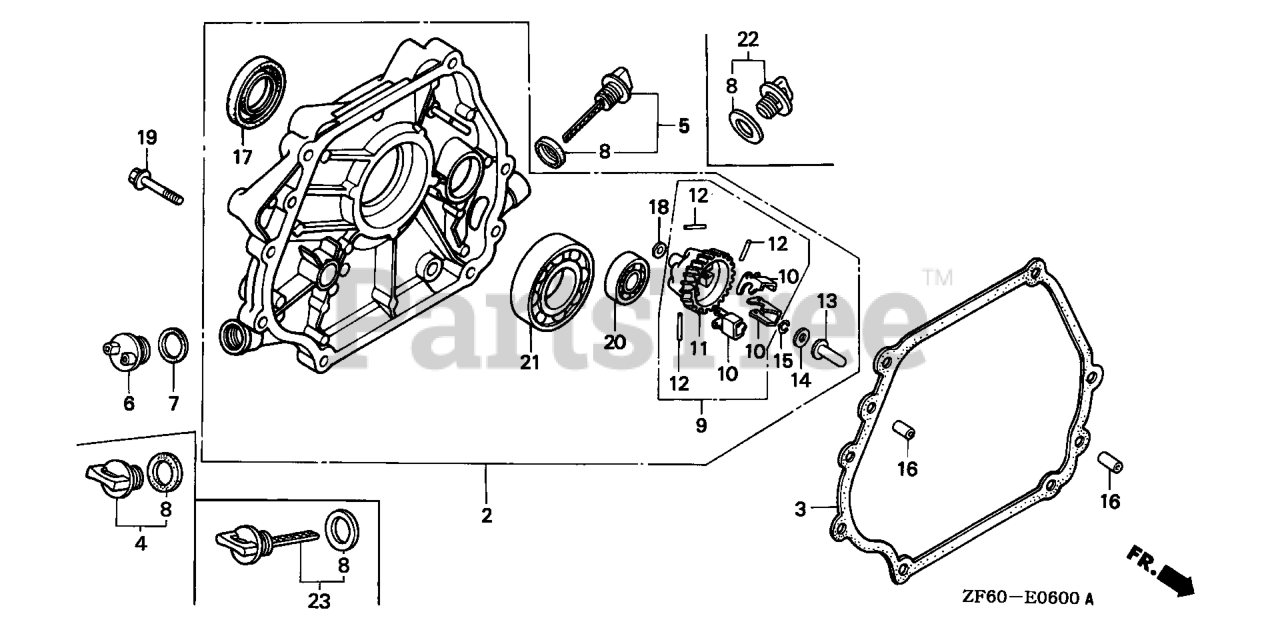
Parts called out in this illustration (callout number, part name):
2	COVER ASSY., CRANKCASE (Q-TYPE)
2	COVER ASSY., CRANKCASE
3	GASKET, CASE COVER Use up to Engine SN 2949254.
3	GASKET, CASE COVER
4	CAP ASSY., OIL FILLER
5	CAP ASSY., OIL FILLER
6	CAP, OIL FILLER
7	GASKET, OIL FILLER CAP Use from Engine SN 1391010.
8	GASKET, OIL FILLER CAP
9	GOVERNOR ASSY.
10	WEIGHT, GOVERNOR
11	HOLDER, GOVERNOR WEIGHT
12	PIN, GOVERNOR WEIGHT
13	SLIDER, GOVERNOR
14	WASHER (6X16)
15	CLIP, GOVERNOR HOLDER
16	PIN, DOWEL (8X12)
17	OIL SEAL (35X52X8)
18	WASHER, PLAIN (6MM)
19	BOLT, FLANGE (8X40) Use up to Engine SN 1003236.
20	BEARING, RADIAL BALL (6202)
21	BEARING, RADIAL BALL (6207)
